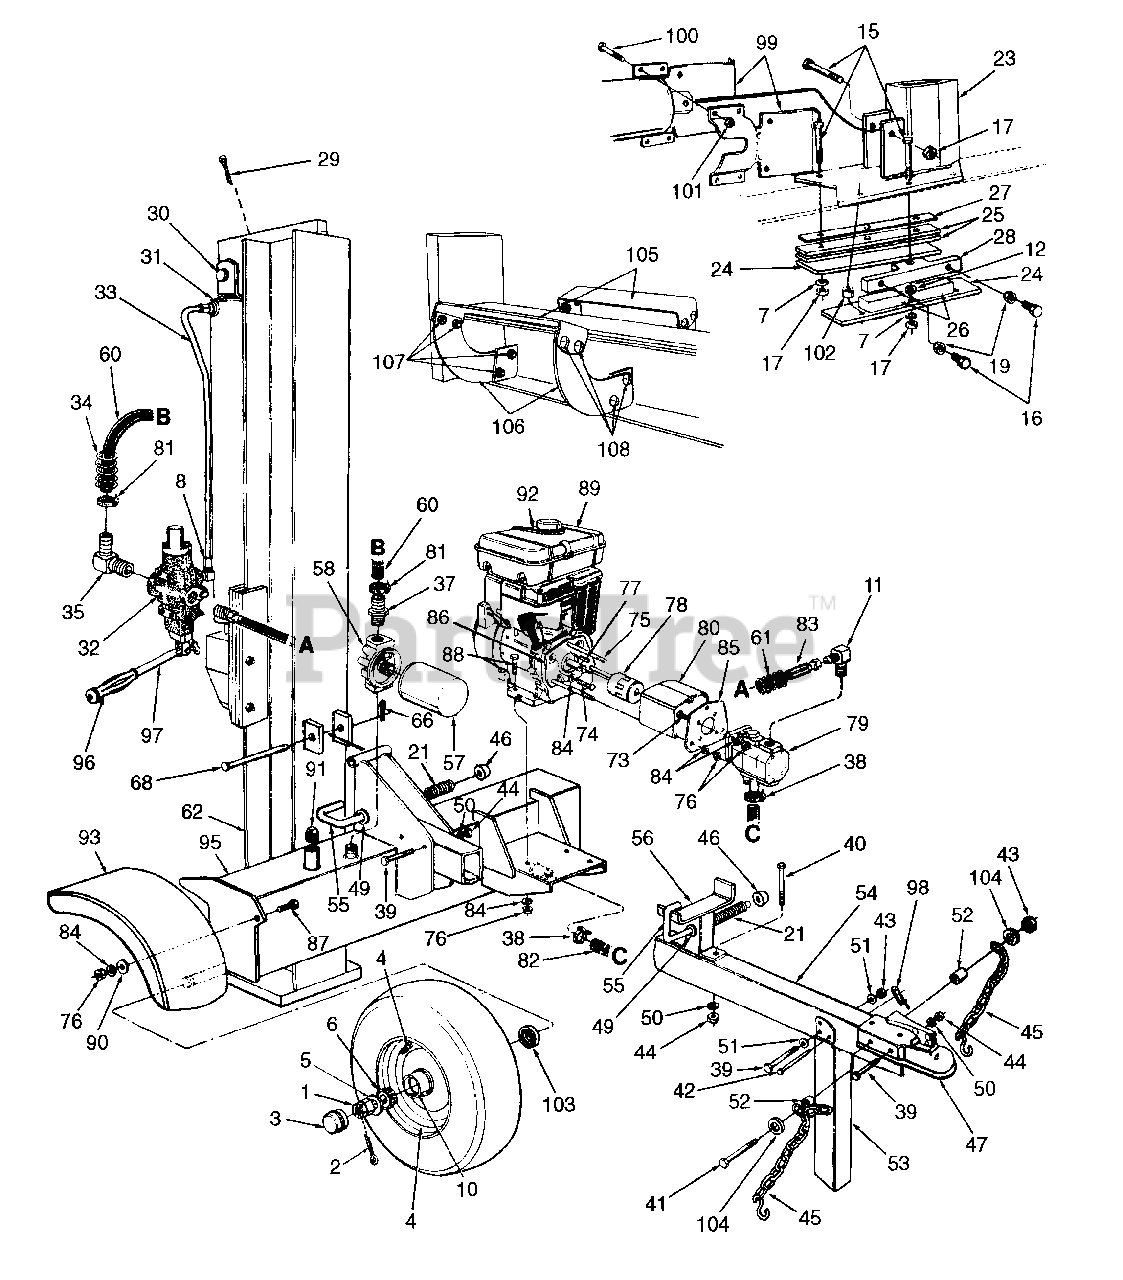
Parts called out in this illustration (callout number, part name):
1	Slotted Nut 3/4-16 Thd.
2	Cotter Pin 5/32" Dia.
5	Fl-Wash. .76" I.D. x 1.5" O.D.
6	Bearing Cone
7	L-Wash. 1/2" I.D.
8	90ø Solid Male Adaptor
10	Bearing Cup
11	90ø Male Adapter
12	Fl-Wash. .531" I.D. x .94" O.D.
15	Hex Bolt 1/2-20 x 2.75 GR8
16	Hex Bolt 3/8-24 x 1.5.
17	Hex L-Nut 1/2-20 Thd.
19	Hex Jam Nut 3/8-24 GR5
21	Comp. Spring 4" Lg.
26	Adjustable Gib
29	Cotter Pin
30	Cylinder Mounting Pin
33	Metal Pressure Tube
34	Hose Guard
35	Return Elbow
37	3/4" Hose Barb.
38	Hose Clamp
39	Hex Bolt 3/8-16 x 3 GR8
40	Hex Bolt 3/8-16 x 4.
41	Hex Bolt 3/8-16 x 4.25 GR5
42	Clevis Pin 5/16 x 2.5" Lg.
43	Hex L-Nut 3/8-16 Thd.
44	Hex Nut 3/8-16 Thd.
45	Chain-tow Hitch
47	Hitch Coupler
49	Fl-Wash. .635" I.D. x .93" O.D.
50	L-Wash. 3/8" I.D.
51	Fl-Wash. .406" I.D. x .75" O.D.
52	Spacer .44" Lg.
55	Locking Rod
57	Filter Element
58	Filter Head
60	Return Hose 3/4" I.D. x 44" Lg.
61	Hose Guard
68	Hinge Pin 1/2 x 4.8
73	Hex Bolt 5/16-24 x 1
74	Hex Bolt 5/16-24 x .62
75	Hex Bolt 5/16-24 x 4
76	Hex Nut 5/16-24 Thd.
77	Sq. Key 3/16" x .75"
78	Flexible Coupling
79	Gear Pump
80	Coupling Shield
81	Hose Clamp 5/8"
82	Suction Hose
83	High Pressure Hydraulic Hose 48"
84	L-Wash. 5/16" I.D.
87	Hex Bolt 5/16-24 x .75
88	Hex Bolt 5/16-24 x 1.75
89	Engine
90	Fl-Wash. .344" I.D. x .875" O.D.
91	L-Vent Pipe Plug
92	Spark Plug Boot
97	Control Handle
98	Spring Pin
101	Insert Lock Nut 3/8-16
102	Spacer 1/2 I.D. x 3/4 O.D. x .68
103	Bearing Seal Only
104	Fl-Wash. 3/8" I.D. x .87" O.D.
108	Carriage Bolt 3/8-16 x 1" Lg.
